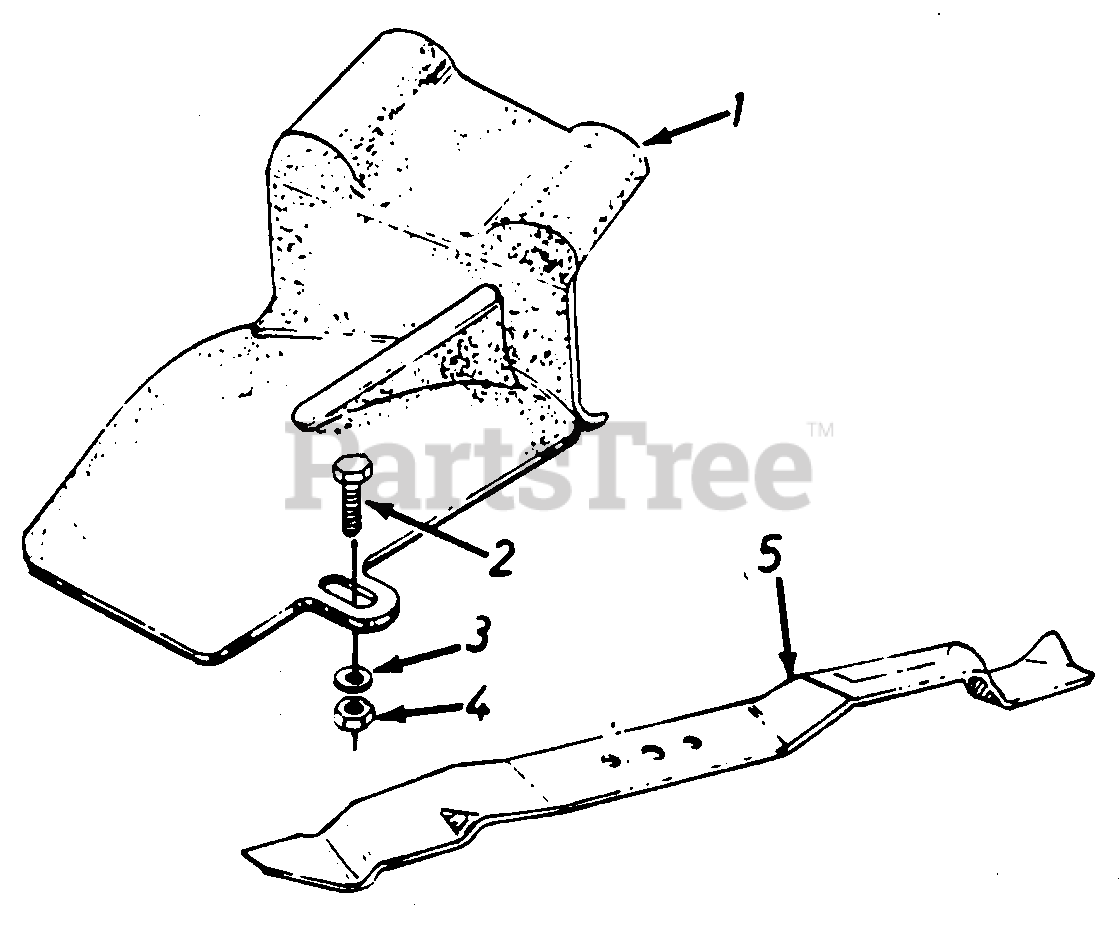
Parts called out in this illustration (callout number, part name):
1	Mulching Baffle
2	Hex Bon 1/4-20 x .88" Lg.*
3	Belleville Wash. .265" I.D. x .75" O.D
4	Hex Jam Nut 1/4-20 Thd.
5	20" Mulching Blade
